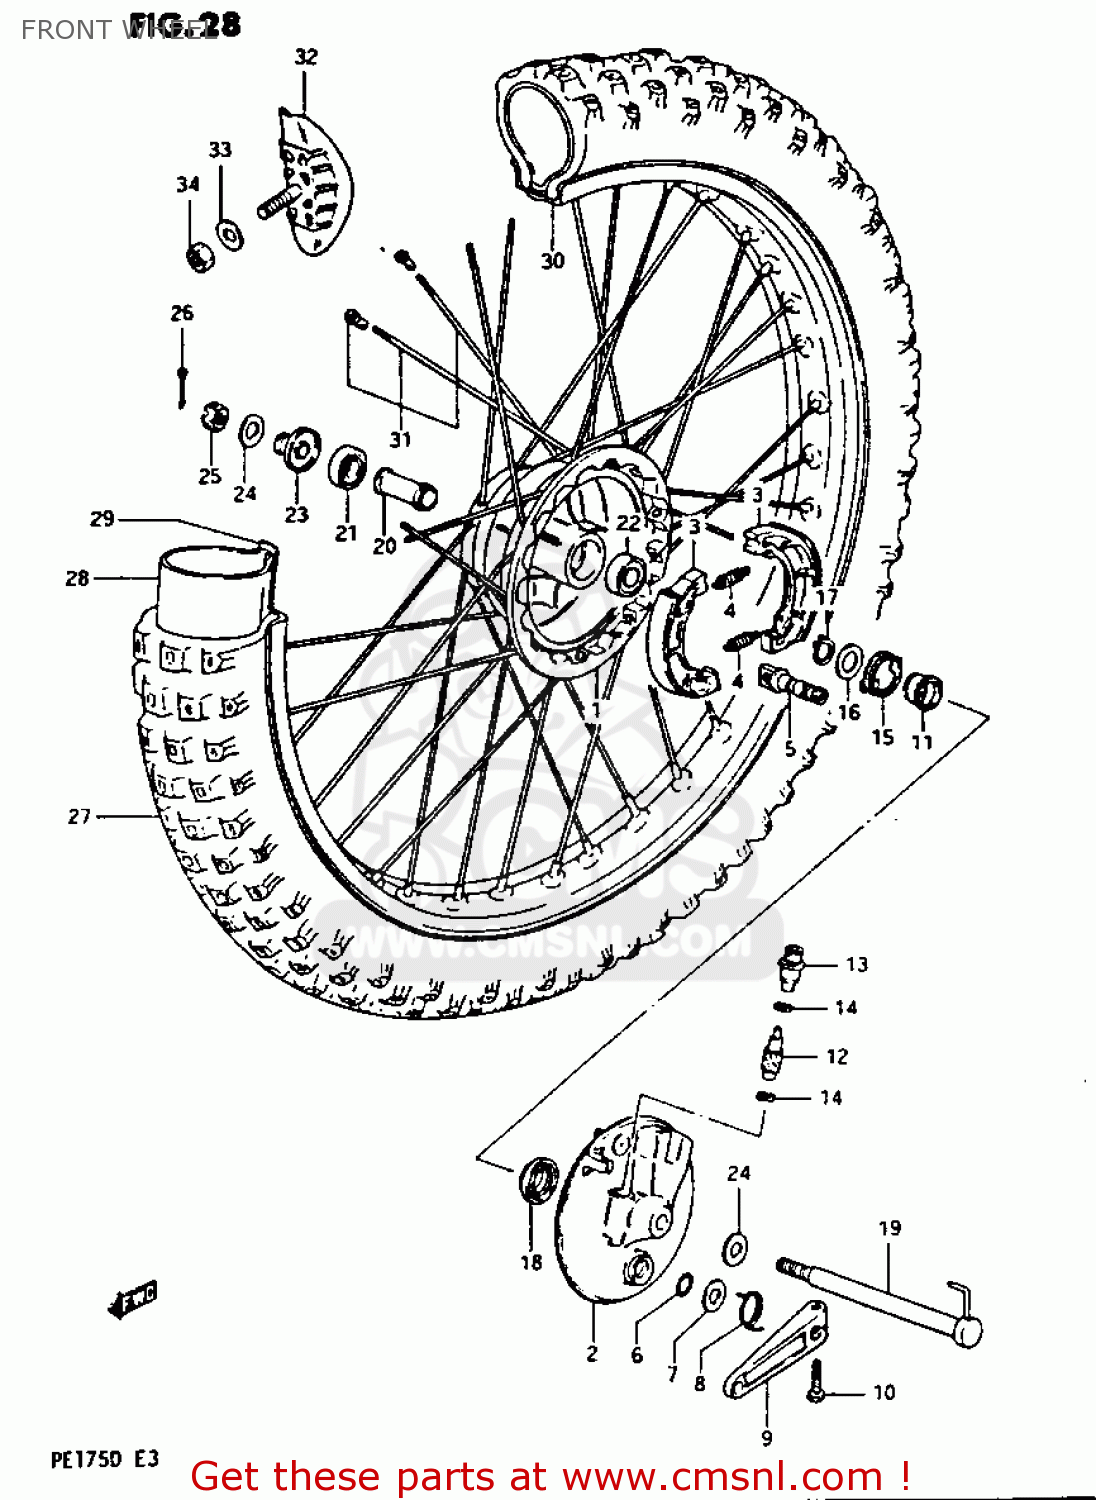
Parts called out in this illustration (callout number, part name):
1	HUB,FRONT
2	PANEL,FRONT HUB
3	SHOE,BRAKE (ASB)
4	SPRING
5	CAM,FR BRAKE
6	O RING(D:2.5,ID:11.4)
7	WASHER(12.5X20X1)
8	SPRING
9	LEVER,FRONT BRAKE CAM
10	BOLT
11	GEAR,SPEEDOMETER
12	PINION,SPEEDOMETER
13	BUSH,SPEEDOMETER PINION OUTER
14	WASHER (5.1X9X0.4)
15	DRIVER,SPEEDOMETER GEAR
16	WASHER(22.5X27X1)
17	CIRCLIP
18	SEAL,OIL(26X38X4)
19	AXLE,FRONT
20	SPACER,FRONT HUB BEARING
21	BEARING
22	BEARING
23	SPACER,FRONT AXLE,RIGHT
24	WASHER
25	NUT, REAR AXLE
26	COTTER PIN
27	TIRE,FRONT
28	TUBE
29	PROTECTOR,WHEEL,INNER
30	RIM,FRONT WHEEL (1.60X21)
31	SPOKE SET,FRONT
32	STOPPER,BEAD
33	WASHER
34	NUT
